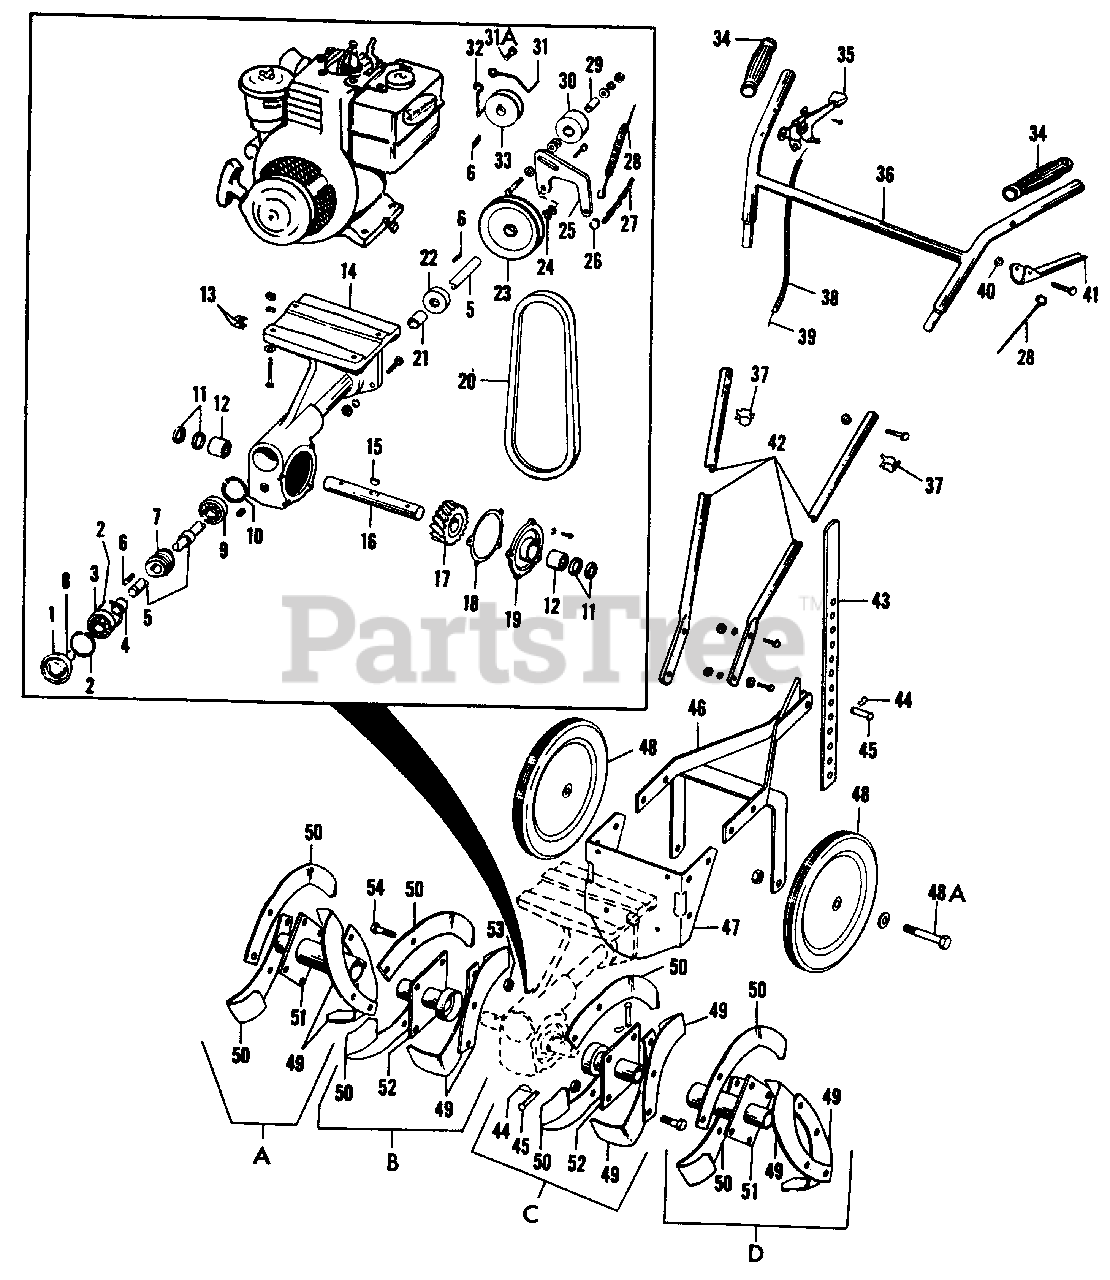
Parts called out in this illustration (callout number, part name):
2	Retaining Ring
3	Ball Bearing
5	Worm Shaft Assembly
8	Retaining Ring
9	Ball Bearing
10	Retaining Ring
12	Needle Bearing
14	Worm Drive Housing
16	Worm Gear Shaft
23	Worm Pulley
24	Full Lock Nut. 5/16-18 NC
25	Idler Lever
26	Retaining Ring
28	Lever Clutch Spring
30	Idler Pulley Assembly
31	Belt Stop
32	Belt Stop
33	Engine Pulley
34	Handle Grip
35	Throttle Lever Control
36	Upper Handle Assembly
37	Cable Clip
38	Throttle Cable
39	Throttle Wire
41	Clutch Grip
42	Lower Handle
43	Depth Bar
44	Spring Clip
45	Pin
46	Rear Frame Assembly
48	Wheel and Tire Assembly
49	R.H. Tine Blade
50	L. H. Tine Blade
51	Outer Tine Plate Assembly
52	Inner Tine Plate Assembly
53	Full Lock Nut, 7/16-20 NF
54	OIL, Worm Gear, 1 Qt Worm Gear Oil
